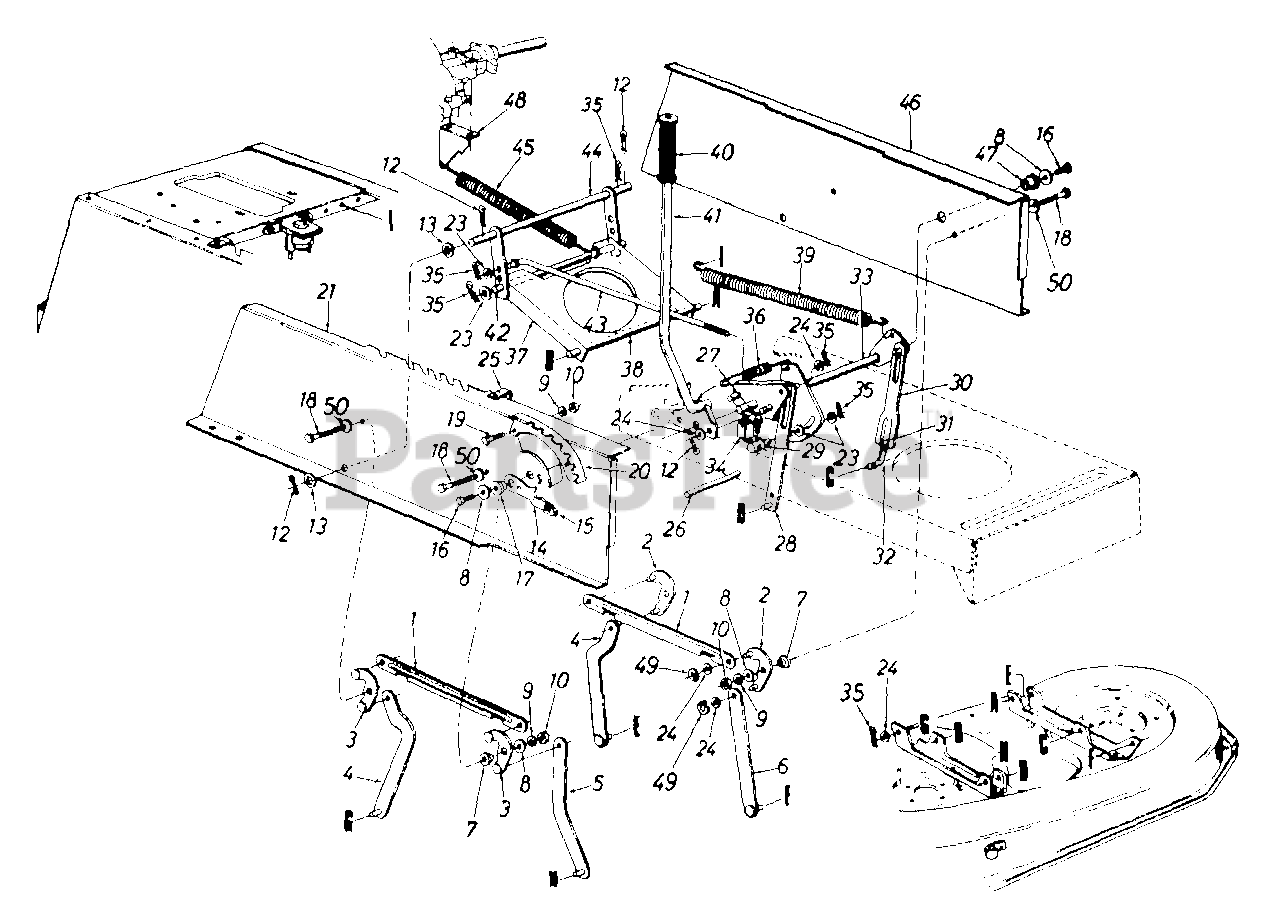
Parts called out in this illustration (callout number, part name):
1	Connecting Rod
2	Pivot Link Ass'y.- L.H. (Uses "E"-Ring)
3	Pivot Link Ass'y.- R.H. (Uses "E"-Ring)
7	Shld. Spacer .318" I.D.
8	Fl-Wash. .344" I.D. x .62" O.D.
9	L-Wash. 5/16" I.D.
10	Hex Nut 5/16-18 Thd.
12	Cotter Pin 1/8" Dia.
13	Fl-Wash. .635" I.D. x 1.0" O.D.
14	Height Adj. Stop Lever Ass'y.
15	Knob
16	Hex Wash. TT-Tap Scr. 5/16-18 x .75" Lg.
17	Flange Brg. .63" I.D.
18	Hex Wash. Hd. Scr. 5/16-18 x .875" Lg.
19	Hex Bolt 5/16-18 x .75" Lg.
20	Index Brkt.
24	Fl-Wash. .531" I.D. x .93" O.D.
25	Clamp
26	Running Board Rod
27	Hex Wash. Hd. Tap Scr.
31	Hex Nut 1/2-20 Thd. (Gr. 5)
32	Lift Link Adjuster
35	Inter. Cotter Pin 3/8" Dia.
36	Extension Spring
39	Extension Spring
40	Grip (Lift Handle)
41	Deck Lift Handle Ass'y.
42	Shaft 3/8" Dia. x 9.34" Lg.
43	Disengagement Rod
44	Stabilizer Shaft Ass'y.
45	Extension Spring 7.58" Lg.
46	Upper Frame - L.H.
47	Flange Brg. .632" I.D.
48	Spring Retainer Brkt.
49	"E"-Ring
50	Bell-Wash. .325" I.D.
